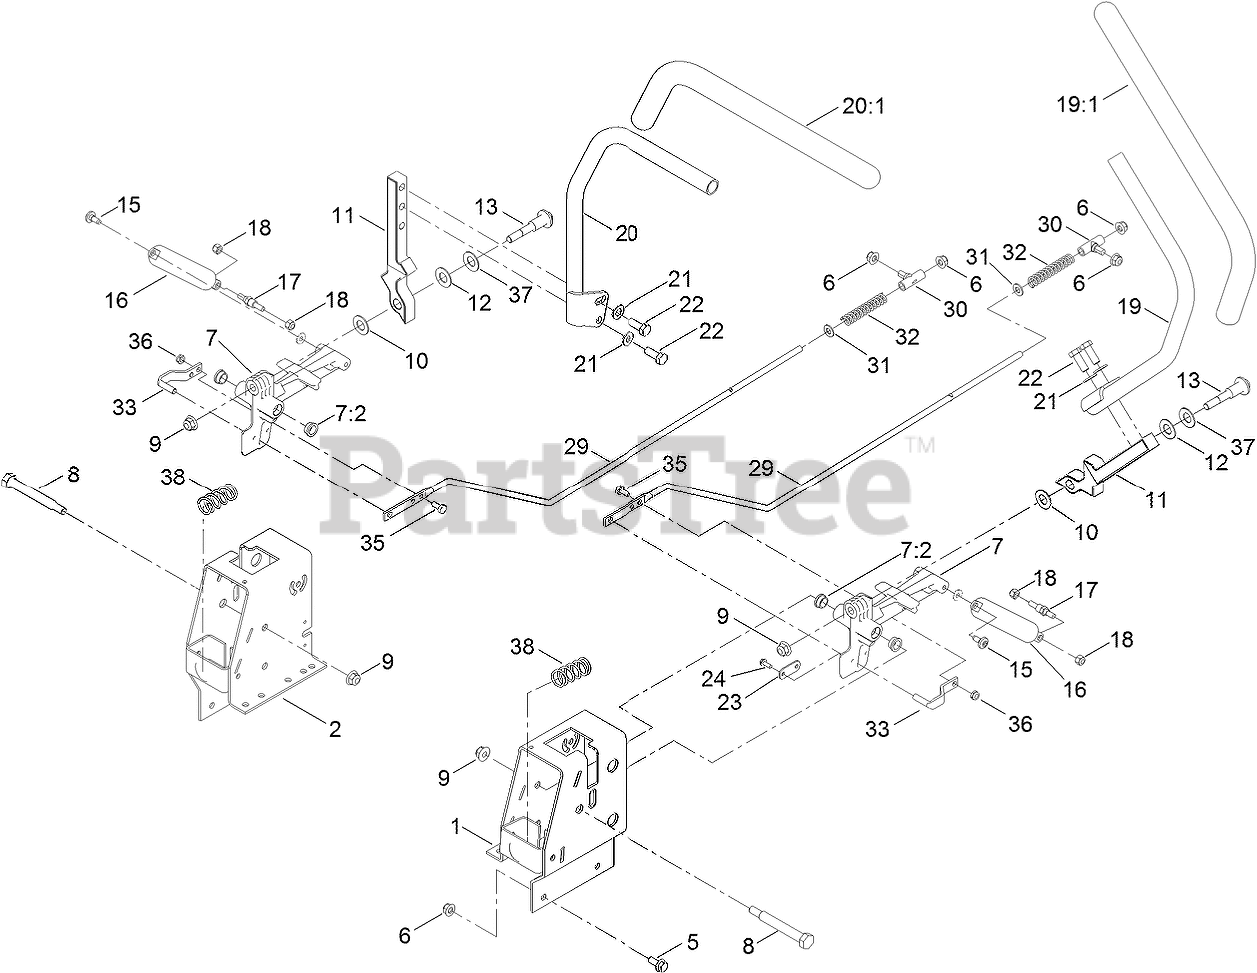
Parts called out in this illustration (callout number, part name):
1	BOX-CONTROL, LH
2	BOX-CONTROL, RH
5	SCREW-HHF
6	NUT-HF, NI
7	ACTUATOR ARM ASM
7:2	BUSHING-FLANGE
8	BOLT-PIVOT
9	NUT-HF, NI
10	WASHER-NYLON
11	ARM-CONTROL
12	WASHER
13	BOLT-PIVOT
15	SCREW-SHOULDER
16	DAMPER-NON CAVITATING
17	STUD-DAMPER
18	NUT-LOCK, NI
19	HANDLE-CONTROL, LH
20	HANDLE-CONTROL, RH
21	WASHER-FLAT
22	SCREW-HH
23	PLATE-STOP, HYDRO
24	SCREW-TAPTITE
29	ROD-HYDRO
30	MOUNT-ROD, HYDRO
31	WASHER-PLAIN
32	SPRING-COMPRESSION
33	PIN-ROD, HYDRO
35	SCREW-HH
36	NUT-LOCK, NI
37	WASHER-BELLEVILLE
38	SPRING-RETURN
